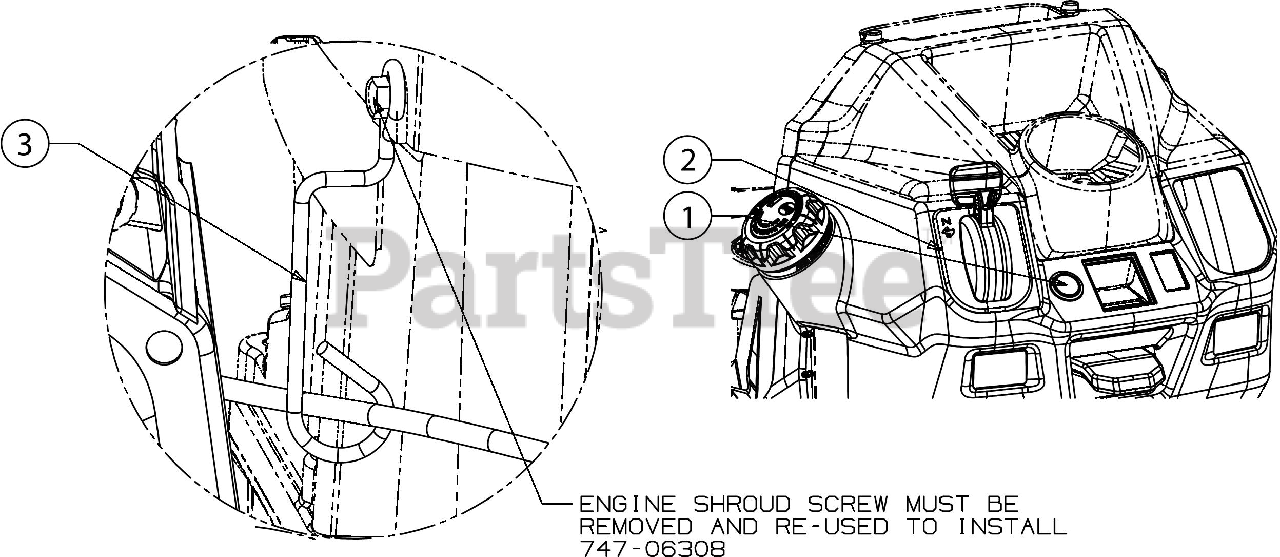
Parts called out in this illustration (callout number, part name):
1	CHOKE PLUG
2	THROTL/CHOKE CABLE 43.5X1.7
3	CABLE GUIDE WIRE
